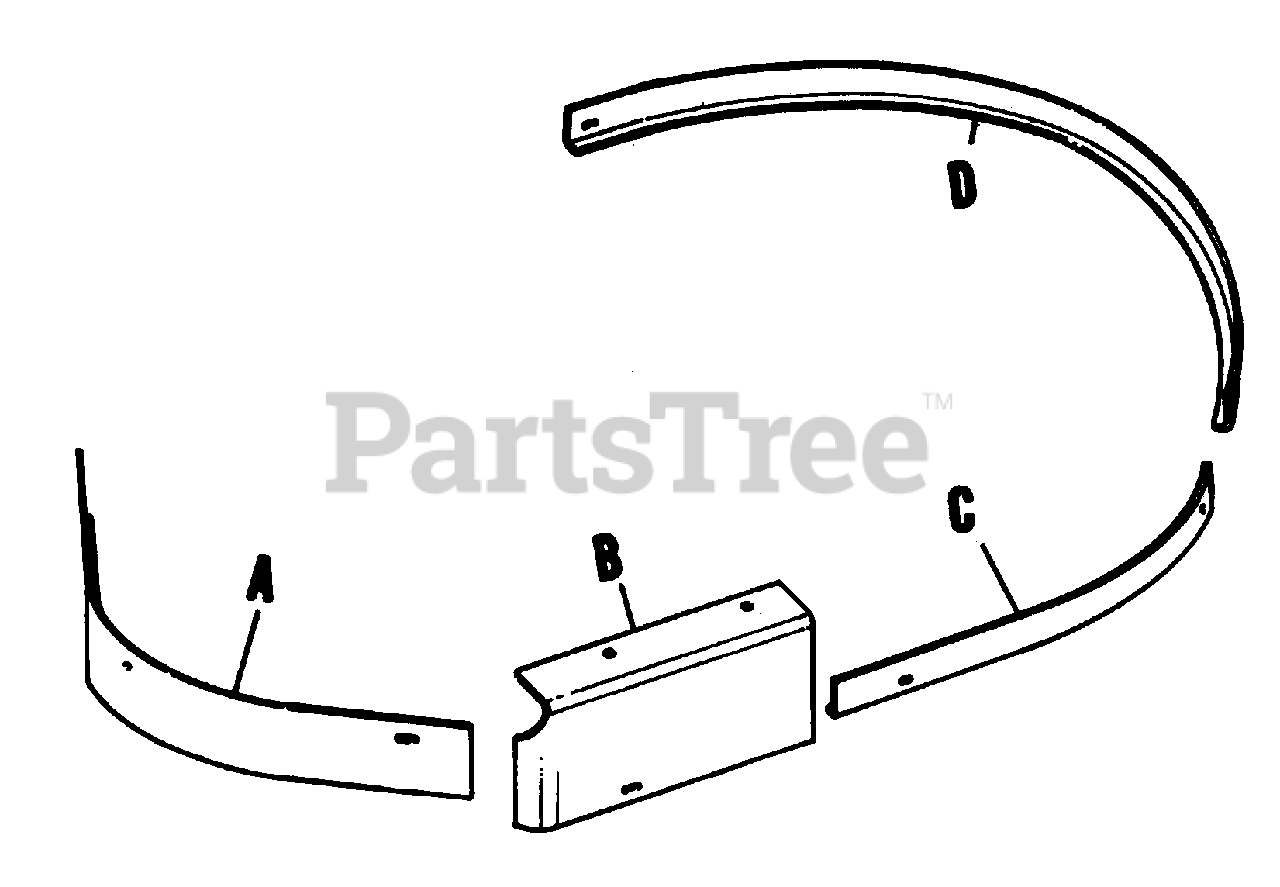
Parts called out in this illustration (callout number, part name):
A	Baffle, Front
B	Baffle, Side
C	Baffle, Left Hand Rear
D	Baffle, Rear
